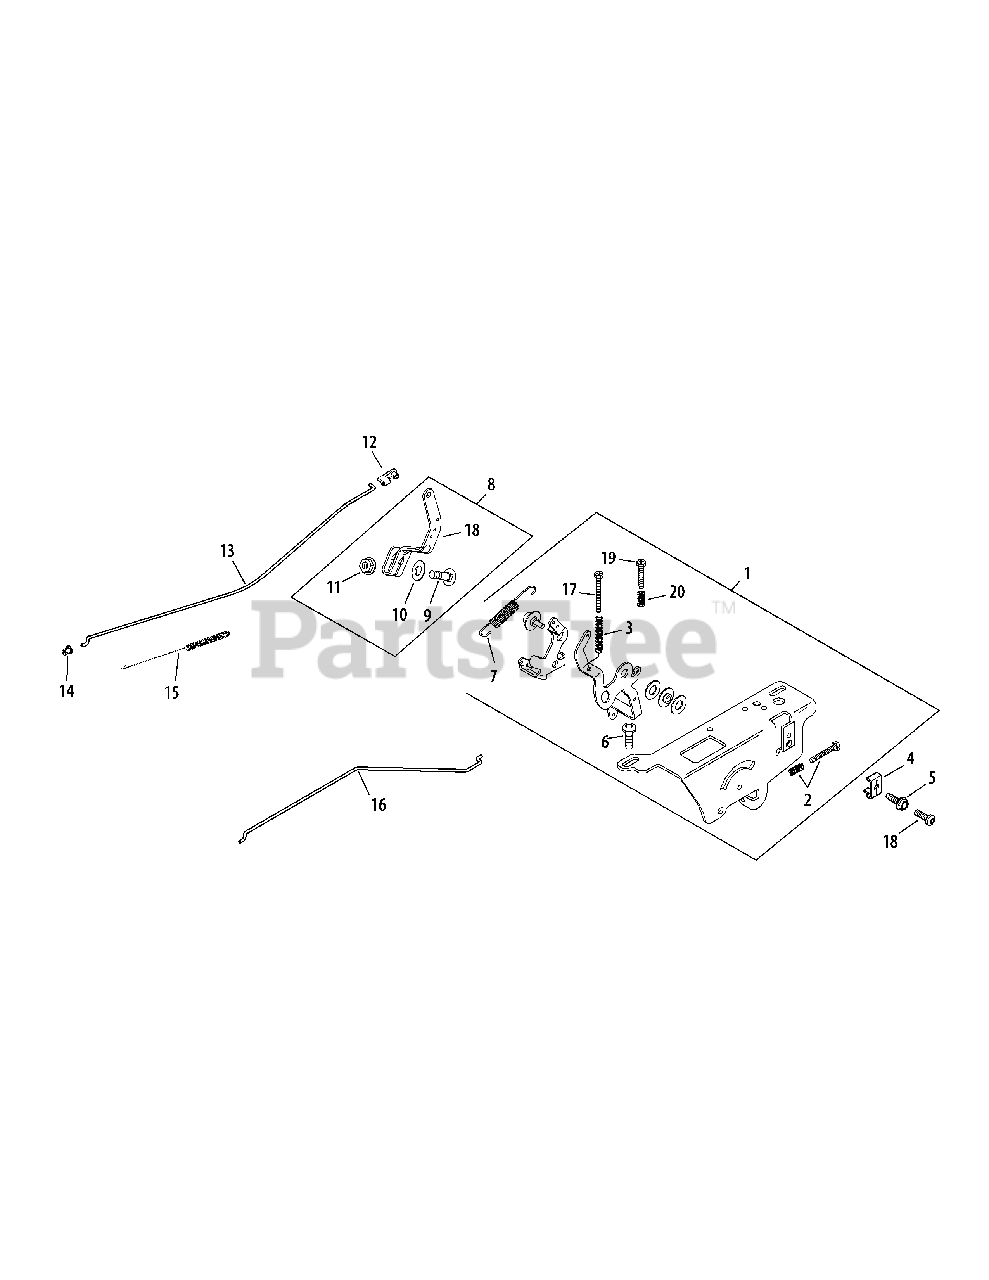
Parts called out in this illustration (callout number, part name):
1	Speed Control Assembly Kit
2	Idle Adj. Screw & Spring Kit
3	Speed Control Spring (Long)
4	Cable Clamp
5	Thread Forming Screw
6	Lbd. Skt. Screw, M6 X 1.0 X 20
7	Governor Spring
8	Governor Ass’y Lever (Inc. 9-11)
9	Rd. Hd. Sq. Nck. Bolt, 1/4-20 X 1
10	Int. Tooth Lock Washer, 1/4
11	Hex Flg Nut, 1/4-20
12	Throttle Linkage Bushing
13	Throttle Linkage
14	Linkage Retaining Bushing
15	Linkage Spring
16	Choke Linkage
17	Screw, Choke Adj M4 x 0.7 x 38
18	Governor Lever
19	Phl. Thd. Frm. Screw, M4 X 0.7 X 25
20	Speed Control Spring (Short)
